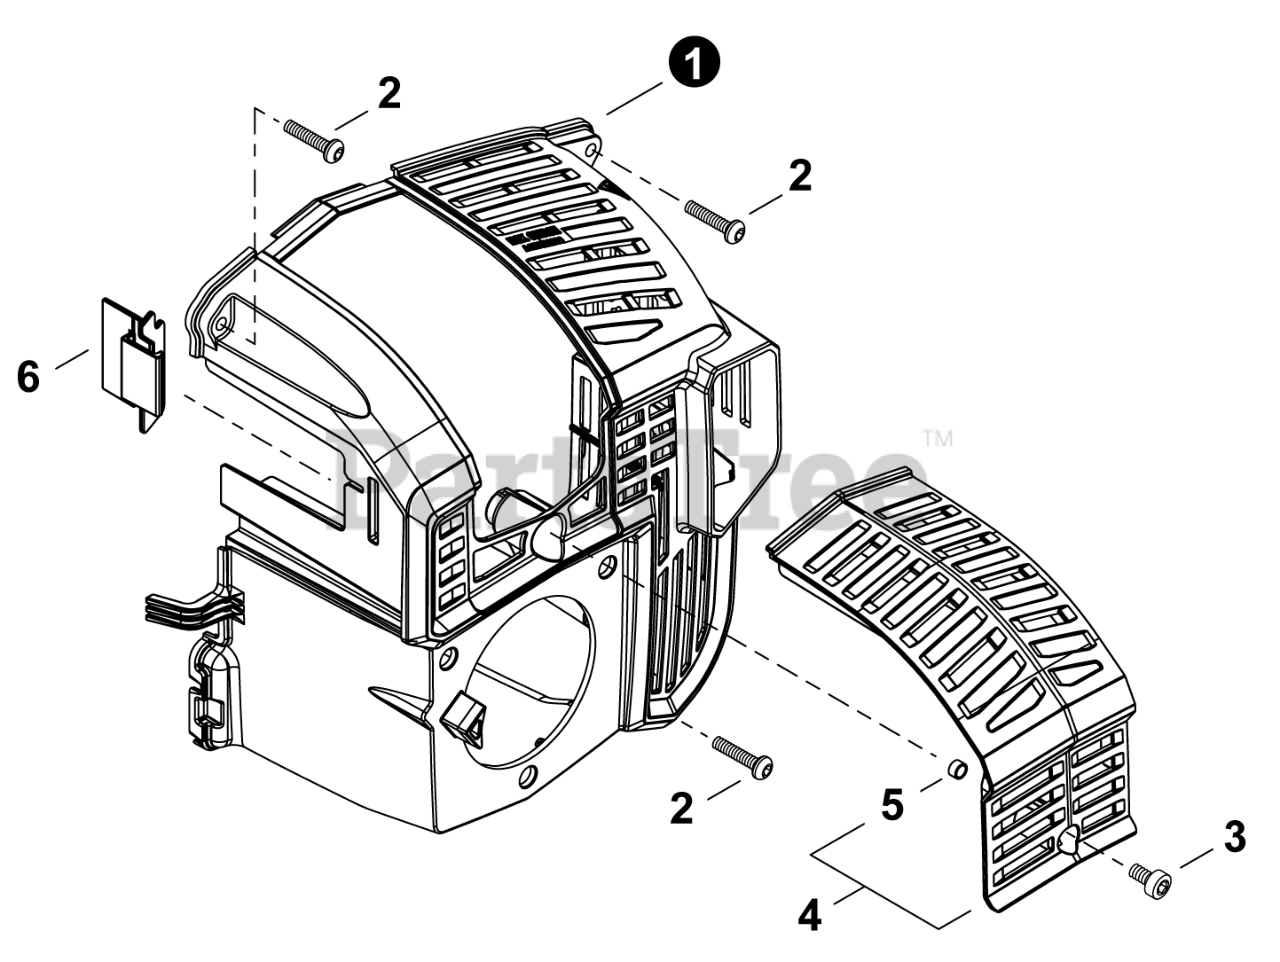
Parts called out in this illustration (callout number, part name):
1	COVER, ENGINE
2	BOLT, TORX 5x20
3	BOLT, TORX 5x12
4	COVER, CYLINDER
6	PLATE, INSULATOR
